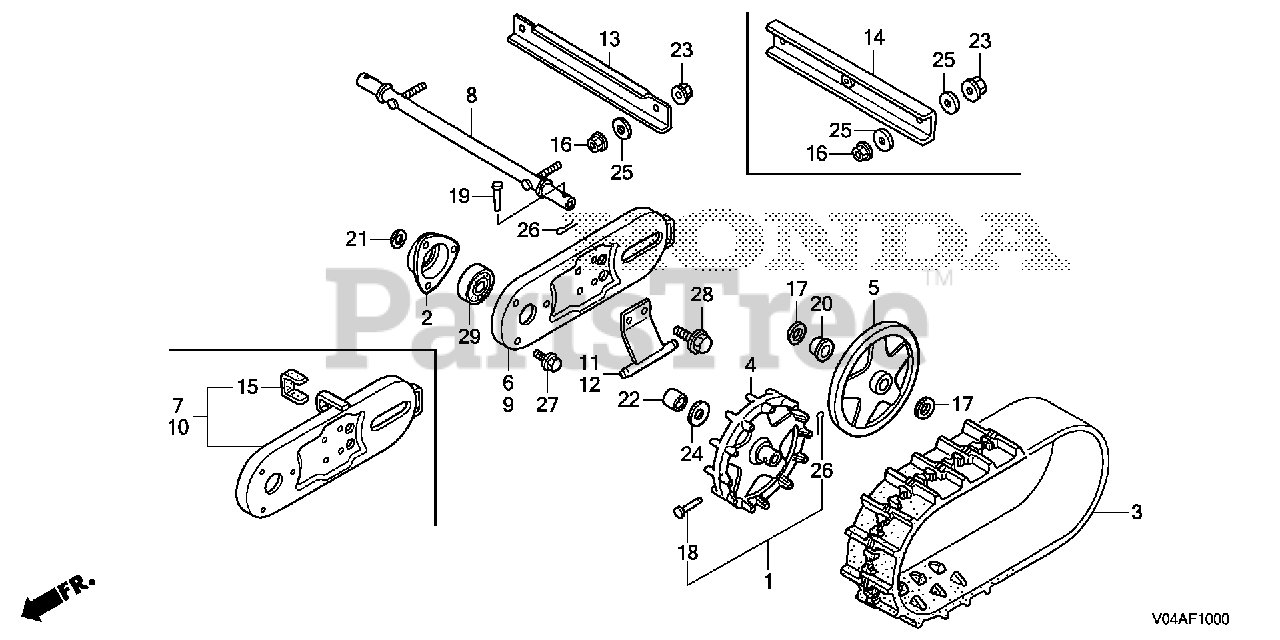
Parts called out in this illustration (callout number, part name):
1	PIN SET, CRAWLER
2	HOLDER, WHEEL SHAFT BEARING
3	CRAWLER (12-60X20 B-122)
4	SPROCKET, CRAWLER
5	ROLLER, CRAWLER
6	PLATE, R. CRAWLER
8	PIPE, CRAWLER
9	PLATE, L. CRAWLER
11	GUIDE, R. CRAWLER
12	GUIDE, L. CRAWLER
13	BAR, CRAWLER PLATE
16	NUT, FLANGE (10MM)
17	WASHER, PLAIN (22MM)
20	COLLAR, CRAWLER PIPE
21	COLLAR, R. WHEEL SHAFT
22	COLLAR, CRAWLER SPROCKET
23	NUT, FLANGE (10MM)
24	WASHER, PLAIN (20MM)
25	WASHER, PLAIN (10MM)
26	PIN, SPLIT (3.0X18)
27	BOLT, FLANGE (6X12)
28	BOLT, FLANGE (8X14)
29	BEARING, RADIAL BALL (6004UU)
